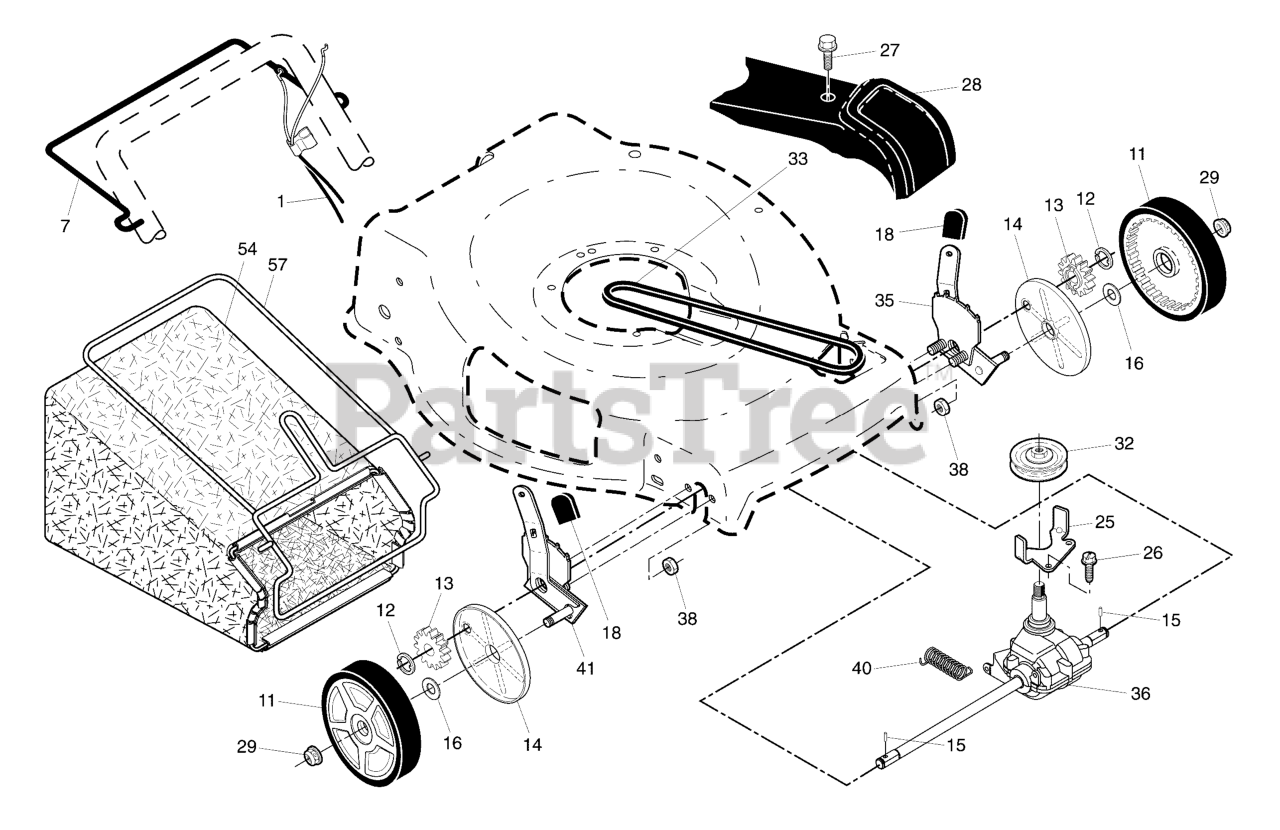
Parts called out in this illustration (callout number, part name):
1	Cable, Drive Control
7	Control Bar, Drive
11	Wheel & Tire Assembly, Front
12	E-Ring
13	Pinion
14	Dust Cover
15	Pawl, Drive
16	Washer, Flat 3/8
18	Selector Knob
25	Belt Keeper
26	Screw, Hi-Lo Thread #12 x 5/8
27	Screw, Pan Head, Self-Tapping #10-24 x #10-24 x 2-3/4
28	Drive Cover
29	Locknut, Hex
32	Drive Pulley
33	V-Belt
35	Wheel Adjuster, Front, LH
36	Gear Case Assembly, Complete
38	Locknut, Hex 1/4-20
40	Spring
41	Wheel Adjuster, Front, RH
54	Grassbag
57	Frame, Grassbag
